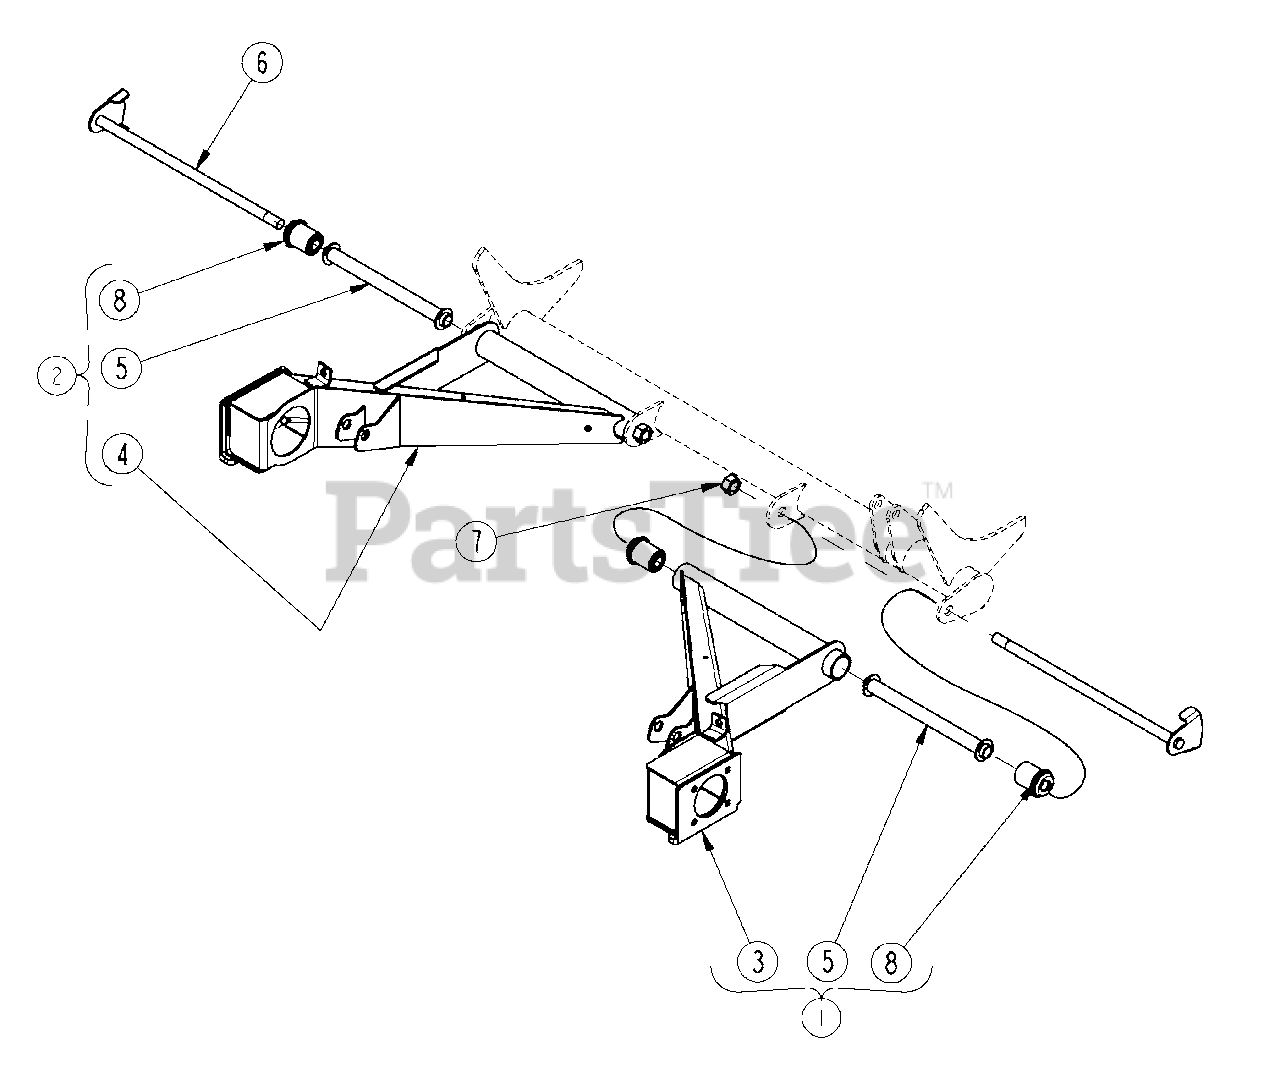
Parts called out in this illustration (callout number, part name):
1	TRAILING ARM RH ASSY
2	TRAILING ARM LH ASSY
3	TRAILING ARM RH WELDMENT
4	TRAILING ARM LH WELDMENT
5	CENTER PIVOT TUBE WELDMENT
6	TRAILING ARM PIVOT BOLT WLDMNT
7	NUT-LK-TOP .563-12 GR5 YWZC
8	BUSHING IDLER ARM RUBBER
